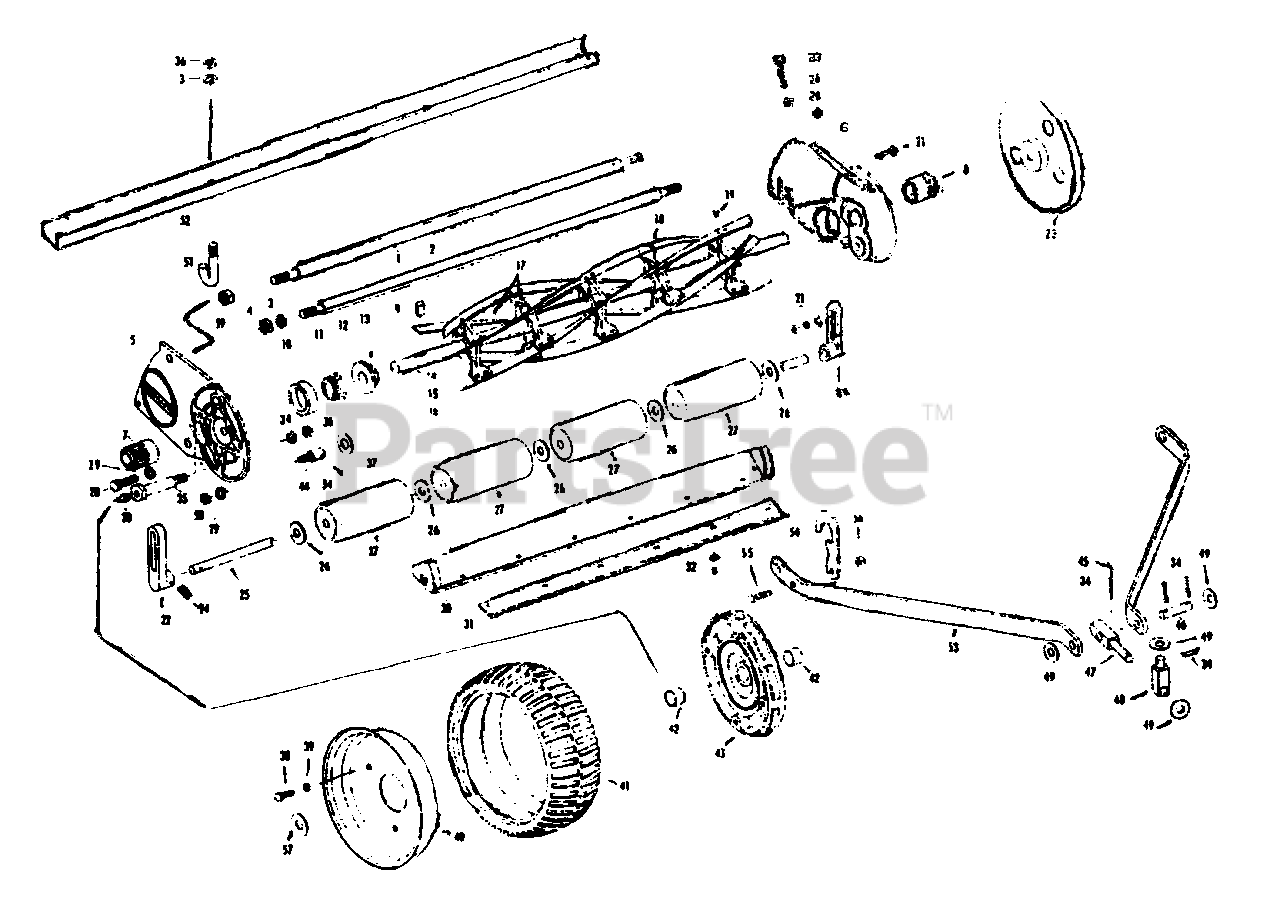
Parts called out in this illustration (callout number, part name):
1	TIE ROD
2	Tie Rod for Front
3	WASHER, Lock 1/2" Regular
4	Hex Nut, Full, 1/2"-13
5	Side Plate, R.H.
6	Side Plate, L.H.
7	Pinion, LH (from Front of Mower)
8	Pinion, RH (from Front of Mower)
10	Bearing Cup for Spiral Cutter
11	Bearing for Spiral Cutter
12	Collar for Spiral Cutter Shaft
13	Screw, Set, Cup Point, Socket Head, 5/16"-18 N.C. x 5/16" lg.
14	Shaft for Spiral Cutter
15	Knife for Spiral Cutter
16	Rivet for Spider
17	Spider, R.H., for Spiral Cutter
18	Spider, L.H., for Spiral Cutter
19	Set Screw for Spider
20	Fitting, Grease, Alemite No. 1641
21	Carriage Bolt, 5/16"-18 x 1-1/4" lg.
21	Plain Washer, 5/16" (Mfg. No. 920)
21	Lockwasher, External 1/4" (Mfg. Nos. 953 & 954)
21	Hex Nut, Full, 5/16"-18" NC (For "725" Only-Rear)
22	Roller Bracket, R. or L.
23	Wheel Cover, R.H.
23	Sealant-Liquid
24	Roll Pin for Roller Brackets
25	Shaft for Roller
26	WASHER, Plain, 1/2" Standard
27	Wood Roller Section (4 Sectional)
28	Capscrew, Hex Hd., 7/16"-14 NC x 1-1/4" lg.
29	Lockwasher 7/16" Henry #918199
30	Knife Bar
31	Lower Knife
32	SEALANT, Liquid
32	Lock Washer, 1/4" (Not used on 308 & 314)
33	Adjusting Screw for Knife Bar
34	Cotter Pins
35	Wheel Stud Assy., w/Nut & Washers
36	Nut, Hex, Full, 1/2"-20 NF
37	Flat Washer
38	Screw, Cap, Hex., 5/16"-18 N.C. x 5/8" lg.
39	Lockwasher, External 1/4" (Mfg. Nos. 953 & 954)
40	Wheel 1/2 Section
41	Tire for Wheel
42	Bearing for Wheel (2 in each Wheel)
43	FUEL STABILIZER 8 OZ
44	FUEL ADDITIVE 16 OZ
50	Hex Nut for Tie Iron Stud
57	Flat Washer
58	Hex Nut, Jam, 3/8"-24
59	Lock Nut, 1/2"-13
